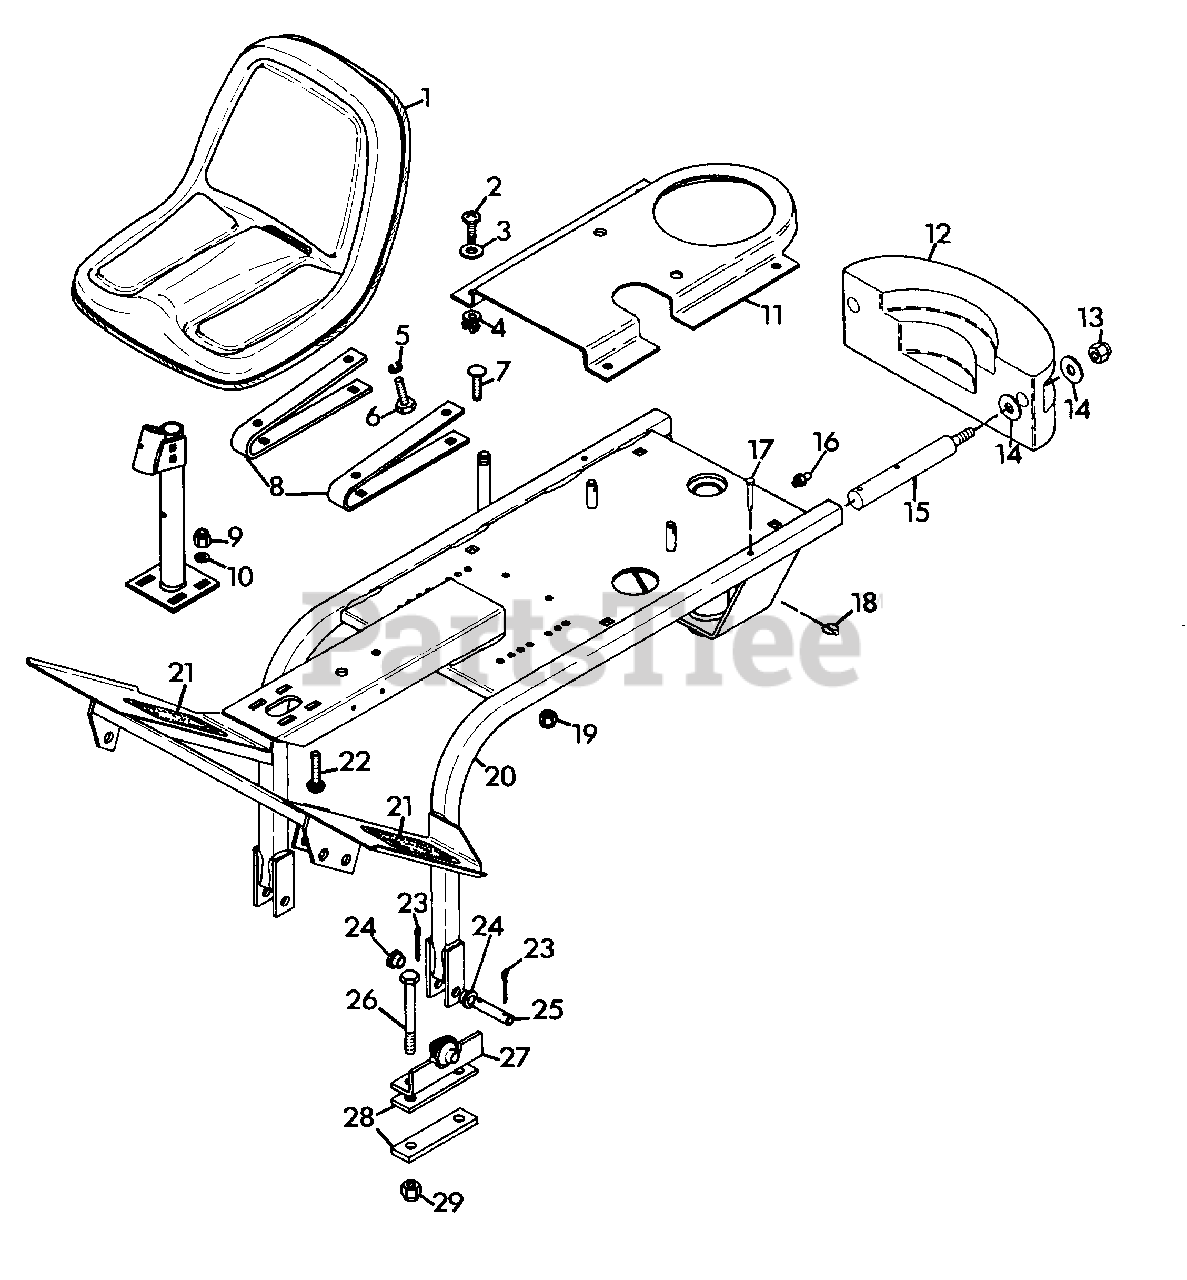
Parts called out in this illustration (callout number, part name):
1	SEAT, HIGH BACK
2	SCREW, TAPPING 1/4-20X.625 PHD
3	WASHER, FLAT .344X.688X.065
4	GROMMET, PLASTIC
5	WASHER, LOCK 5/16 REG.
6	BOLT, HEX 5/16-18X.75
7	BOLT, CARRIAGE 5/16-18X1.00
8	SPRING, SEAT
9	NUT, LOCK 3/8-16
10	WASHER, FLAT .406X.812X.065
11	COVER, CHAIN
12	WEIGHT, PRO MASTER-50
13	NUT, LOCK 3/4-10
14	WASHER, FLAT .813X2.0X.148
15	SHAFT, WEIGHT
16	FITTING, LUBE 1/4-28
17	PIN, CLEVIS .375X2.62
18	PIN, KLIK
19	NUT, LOCK 5/16-18
20	FRAME, O.F.C.
21	COVER, LARGE FOOTBOARD
22	BOLT, 3/8-16X1.00 RD HD SQ NK
23	PIN, COTTER .125X1.500
24	BUSHING
25	PIN, .750X3.3
26	BOLT, HEX 1/2-13X5.50
27	WELDMENT, BRACKET MOUNTING
28	PLATE, AXLE
29	NUT, LOCK 1/2-13
NS	DECAL, GRAVELY LOGO
NS	DECAL, PRO MASTER-50(CONTROLS)
NS	DECAL, AMERICA
NS	DECAL, PRO MASTER LOGO
